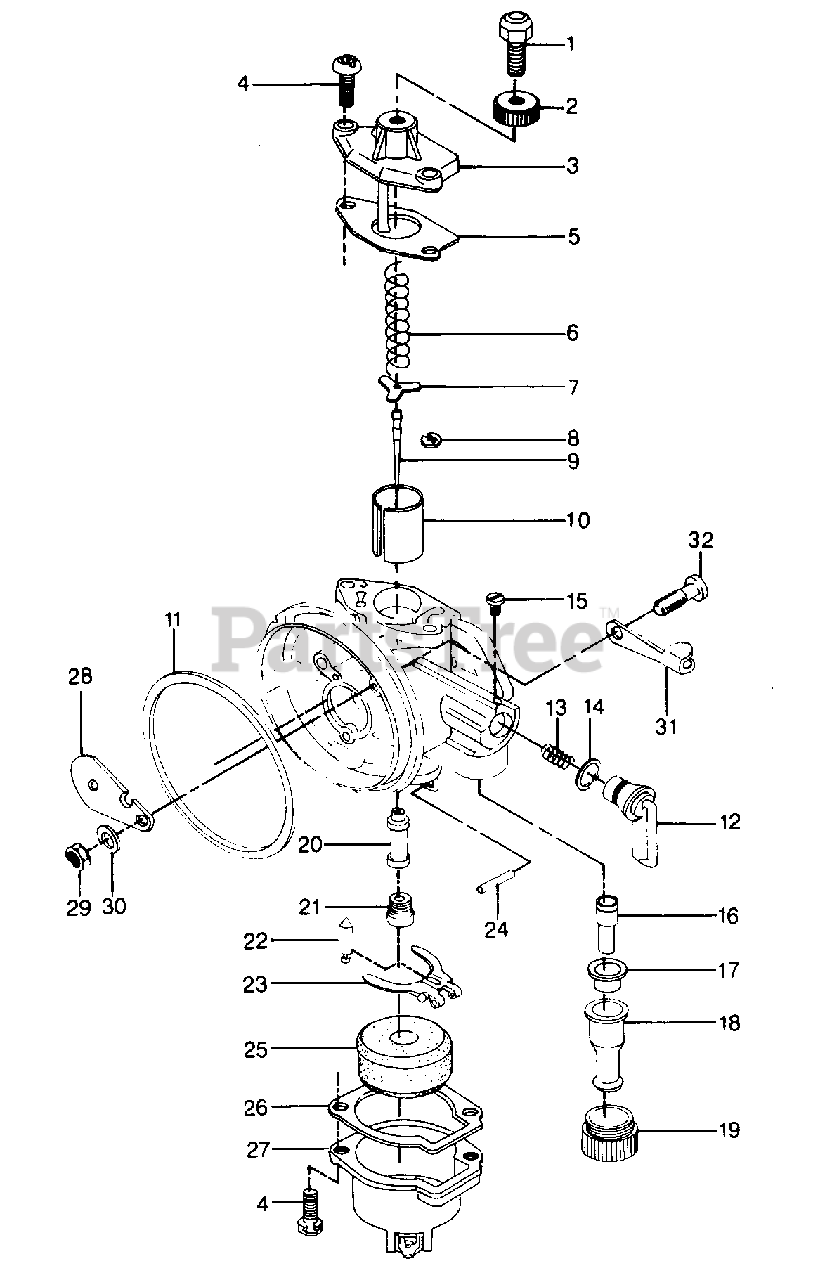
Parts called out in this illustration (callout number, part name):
1	Adjuster - cable
2	Nut - lock
3	Cover - Body
4	Screw (4 x 12mm)
6	Spring - throttle
7	Retainer - spring
9	Needle - jet
10	Valve - throttle
15	Screw - guide
16	Strainer
18	Connector
19	Nut - Connector
20	Jet - needle
21	Jet - main (#88)
22	Valve - needle
23	Hinge, float
24	Pin - float
27	Float Bowl Assembly
28	Valve - choke
30	Washer - spring
31	Lever - choke
32	Bolt - choke
